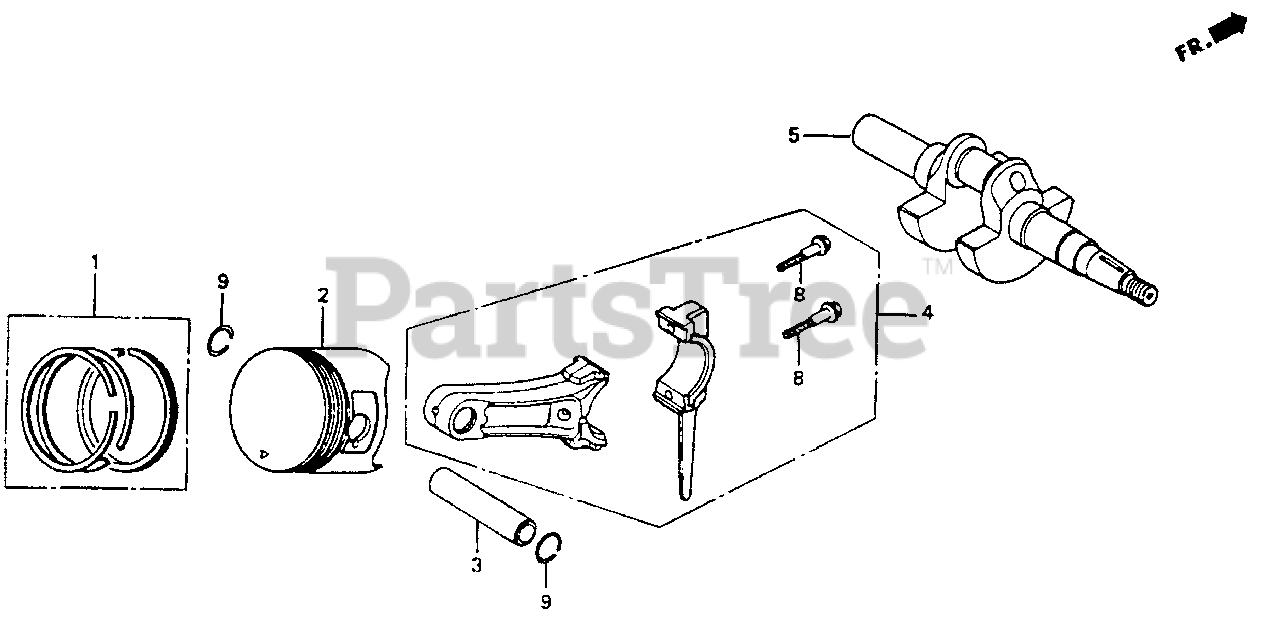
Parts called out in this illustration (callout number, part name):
1	RING SET, PISTON (STD) (NIPPON)
1	RING SET, PISTON (STD) (TEIKOKU)
1	RING SET, PISTON (OS 0.25) (NIPPON) Use up to Engine SN 2120317.
1	RING SET, PISTON (OS 0.25) (TEIKOKU) Use up to Engine SN 2120317.
1	RING SET, PISTON (OS 0.50) (NIPPON) Use up to Engine SN 2120317.
1	RING SET, PISTON (OS 0.50) (TEIKOKU) Use up to Engine SN 2120317.
1	RING SET, PISTON (OS 0.75) (NIPPON) Use up to Engine SN 2120317.
1	RING SET, PISTON (OS 0.75) (TEIKOKU) Use up to Engine SN 2120317.
1	RING SET, PISTON (OS 0.25) (NIPPON)
1	RING SET, PISTON (OS 0.50) (NIPPON)
1	RING SET, PISTON (OS 0.50) (TEIKOKU)
1	RING SET, PISTON (OS 0.75) (NIPPON)
2	PISTON (STD)
2	PISTON (OS 0.25)
2	PISTON (OS 0.50)
2	PISTON (OS 0.75)
3	PIN, PISTON
4	ROD ASSY., CONNECTING (0.25 LOWER SIZE)
4	ROD ASSY., CONNECTING (STD)
5	CRANKSHAFT
8	BOLT, CONNECTING ROD
9	CLIP, PISTON PIN (18MM)
